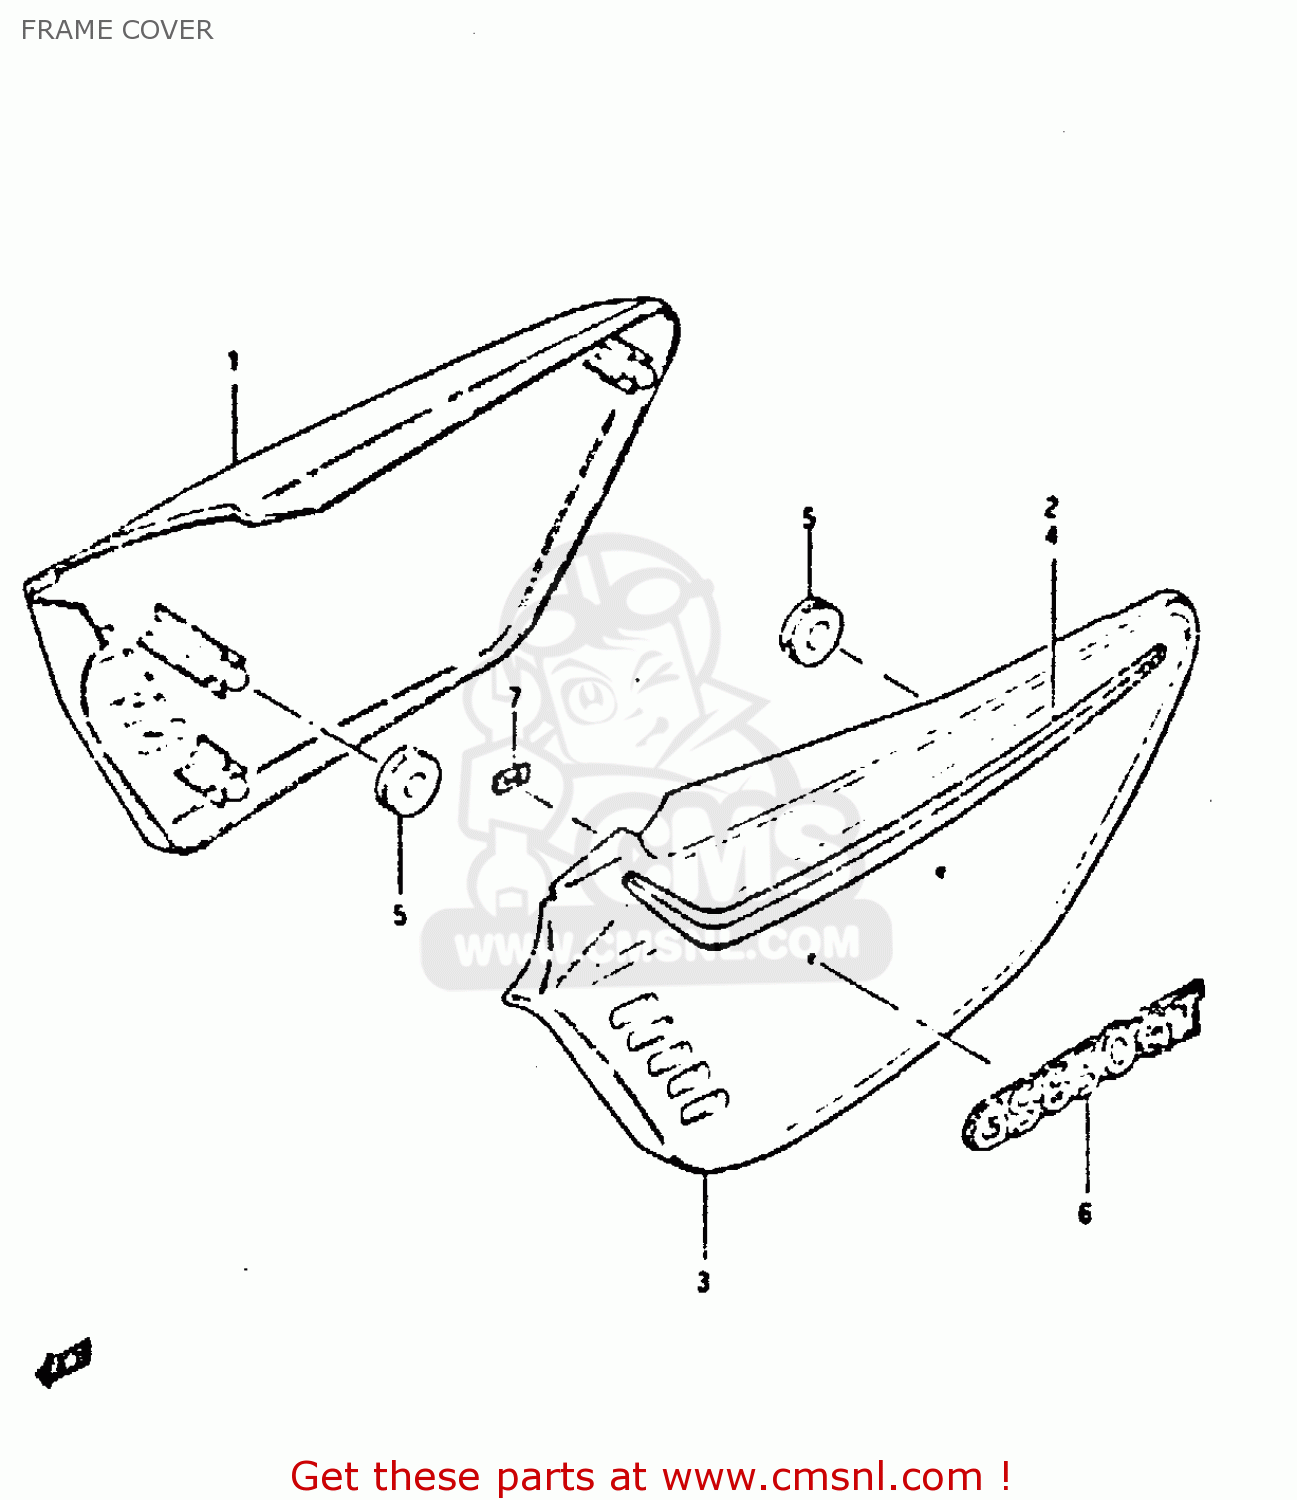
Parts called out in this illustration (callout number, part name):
1	COVER,FRAME,RIGHT
2	TAPE SET,FRAME COVER
3	COVER,FRAME,LEFT
4	TAPE SET,FRAME COVER
5	CUSHION
6	EMBLEM
7	NUT
